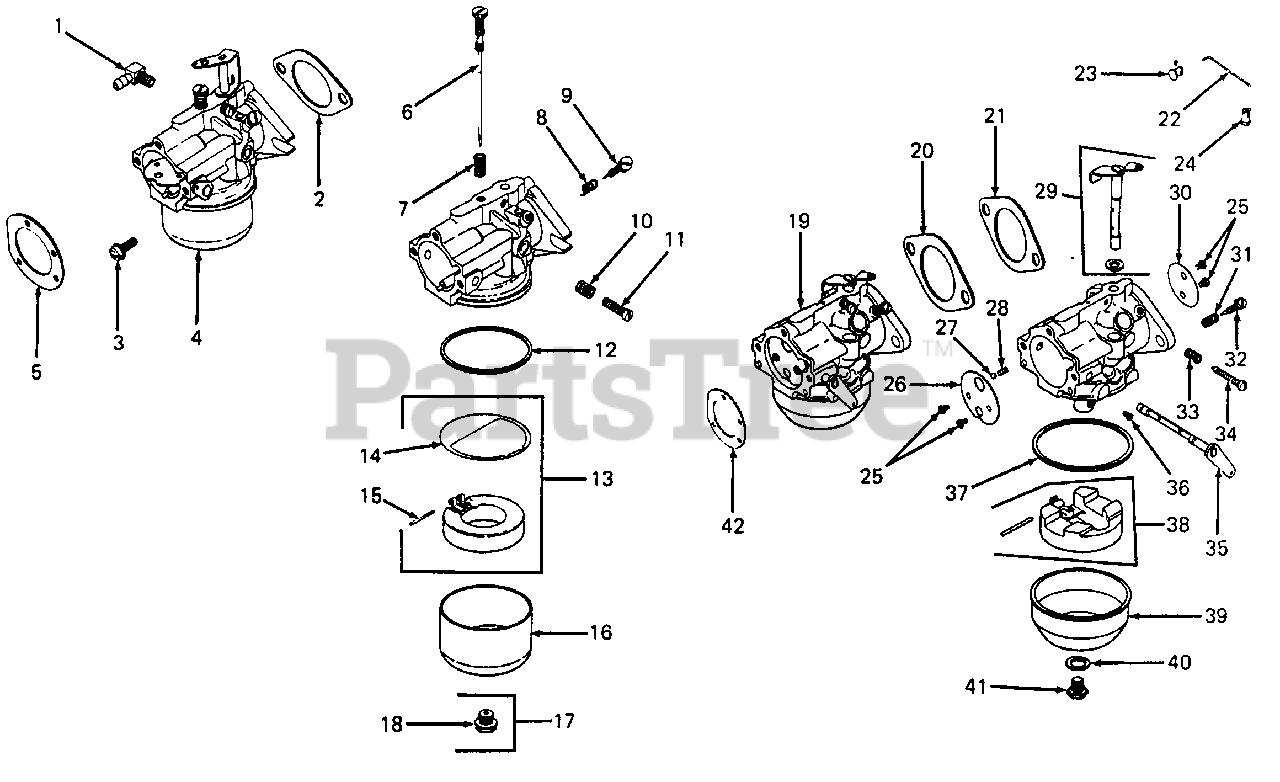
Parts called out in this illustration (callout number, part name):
1	Connector, 90
2	Gasket, Carburetor
3	Screw, Sltd Hd, 5/16-18 X 1.0 Lg
4	Carburetor Assembly
5	Gasket, Air Cleaner
6	Needle, Main Fuel Adj
7	Spring, Main Fuel
8	Spring, Idle Fuel
9	Needle, Idle Fuel Adj
10	Spring, Idle Speed
11	Screw, Idle Speed Adj
12	Gasket, Bowl
13	Kit, Float
14	Gasket, Bowl Baffle
15	Pin, Float Hinge
16	Bowl, Fuel
17	Screw, Bowl Retainer
18	Gasket, Bowl Retainer Screw
19	Kit, Carburetor w/Linkage
20	Gasket, Carburetor
21	Gasket, Carburetor
22	Linkage, Carburetor
23	Bushing, Linkage Retaining - Yellow
24	Bushing, Linkage Retaining - White
25	Screw, Throttle & Choke Plate
26	Plate, Choke
27	Ball, Choke Friction
28	Spring, Choke Friction
29	Shaft, Throttle w/Lever & Seal
30	Plate, Throttle
31	Spring, Idle Fuel
32	Needle, Idle Fuel Adj
33	Spring, Idle Speed
34	Screw, Idle Speed Adj
35	Lever, Choke
36	Jet, Main
37	Gasket, Bowl
38	Kit, Float
39	Bowl, Fuel
40	Gasket, Bowl Retainer Screw
41	Screw, Bowl Retainer
42	Gasket, Air Cleaner
